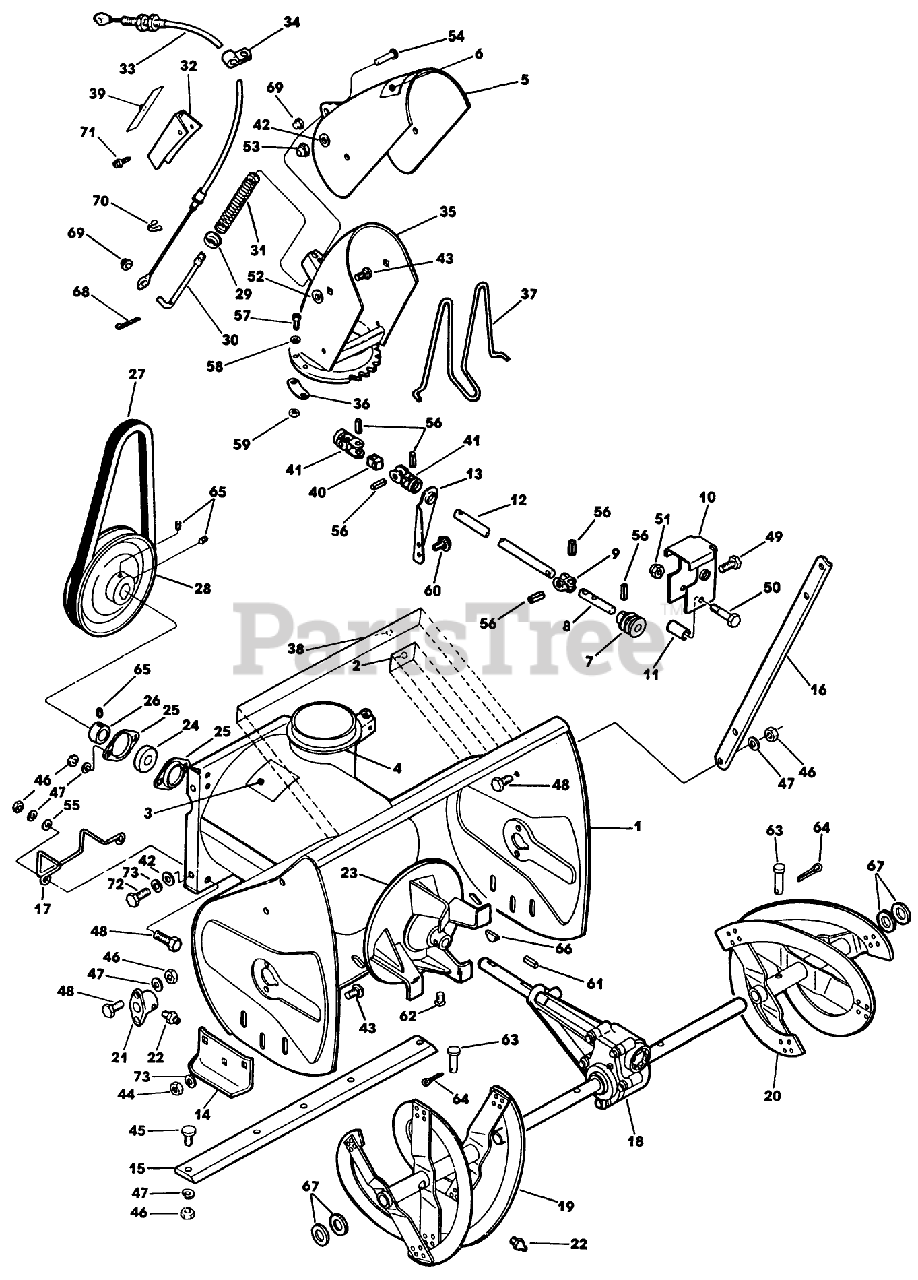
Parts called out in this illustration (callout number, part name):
17	LWR AUGER BELT GUIDE
18	GEAR CASE ASSEMBLY
19	AUGER AY-R.H.
20	AUGER AY-LH *B
24	DISCONTINIUED
25	FLANGETTE-BEARING
26	COLLAR-BEARING
27	V-BELT
28	PULLEY ASM
36	HOLD DOWN CHUTE
40	PIVOT PIN
42	WASHER
44	NUT
46	NUT SS
48	SCREW - HEX
51	NUT-LOCK, CONE
53	NUT-LOCKING
57	SCREW
58	WASHER - LOCKING
60	SCREW-HWH
63	PIN-SHEAR
65	SET SCREW
66	KEY
70	RET. RING
71	SCREW S
73	WASHER
